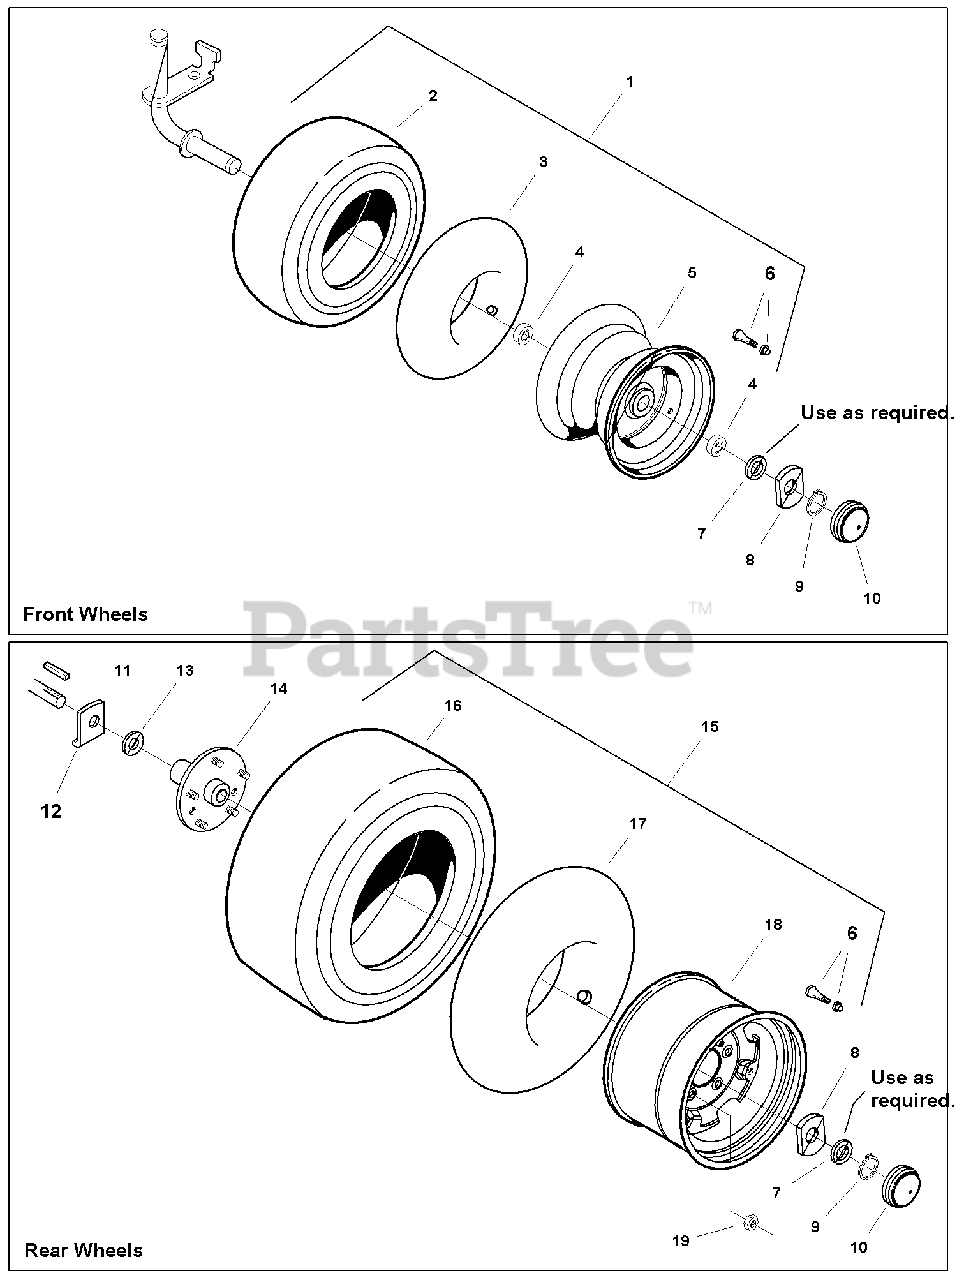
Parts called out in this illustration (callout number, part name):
1	WHEEL & TIRE ASSEMBLY, Front (Includes Ref. 2, 3, 4, 5 & 6)
2	TIRE, 16 x 6-1/2, 8 Super Turf, Front
3	TUBE, Tire 16 x 6 1/2 - 8, Front
4	BEARING, Ball
5	WHEEL, 5-3/8 x 7-15/16, Front
6	VALVE STEM & CAP ASSEMBLY, Air
7	WASHER, 1
8	WASHER, Special, 1 x 2-1/2
9	RING, Retainer
10	CAP, Hub Grey
11	KEY, HI PRO, 1/4 x 2
12	WASHER, Axle Seal "L", 2-1/2 x 2-17/32
14	PLATE & HUB ASSEMBLY, Rear Wheel
15	WHEEL & TIRE ASSEMBLY, Rear 23" (Includes Ref. 6, 16, 17 & 18)
16	TIRE, 23 x 10 1/2 - 12 Super Turf, Rear
17	TUBE, Tire 23 x 10 1/2 - 12, Rear
18	WHEEL, 7 x 12, Rear
19	NUT, Hex, 7/16-20, For Wheel Bolt
